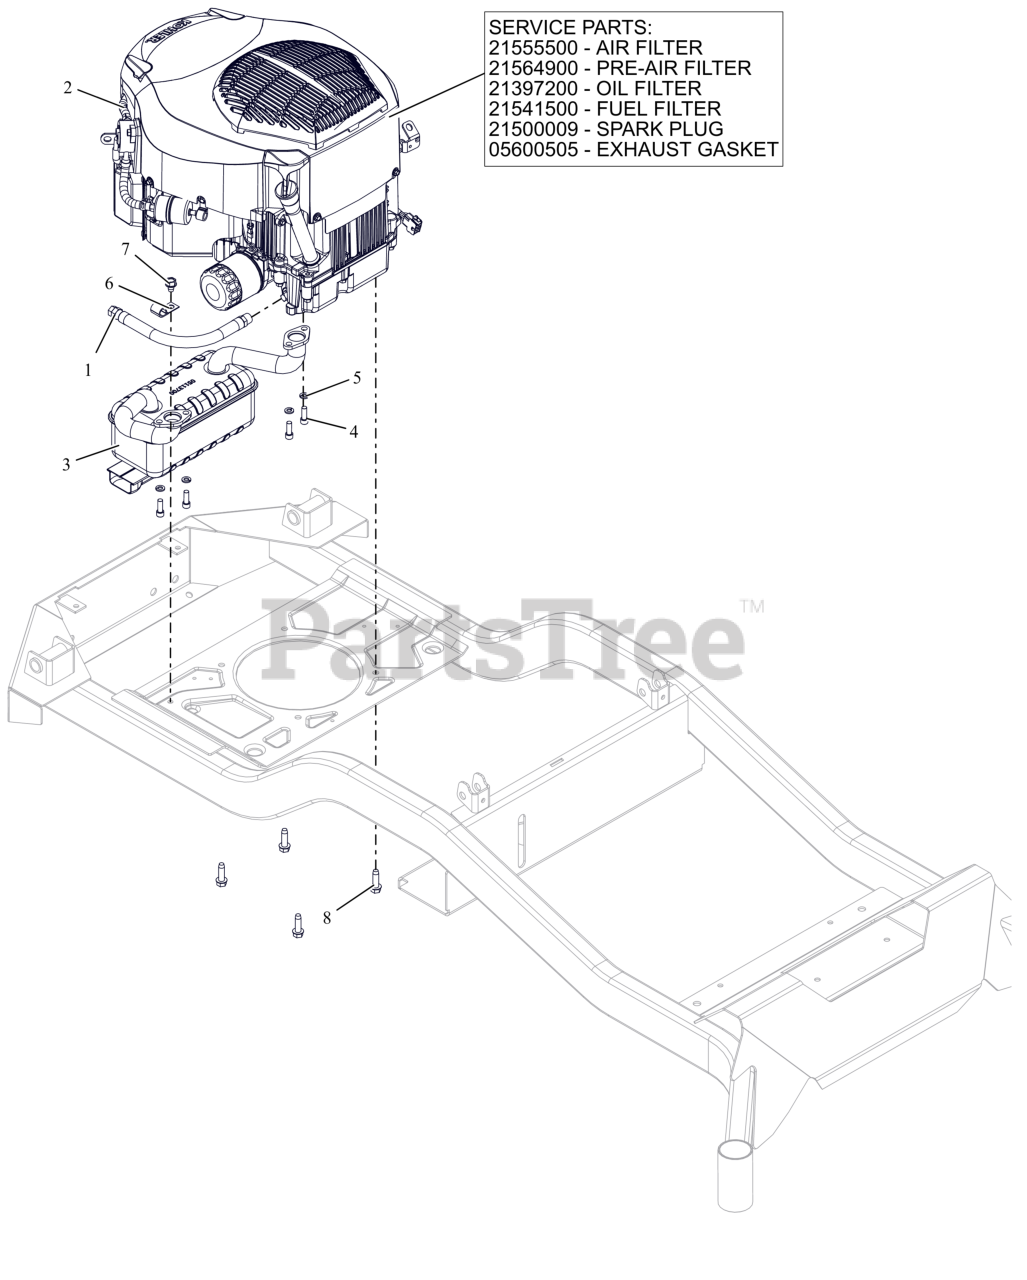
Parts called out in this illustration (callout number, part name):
1	Hose, Oil Drain
2	ENGINE, KOHLER - KT730
2	AIR CLEANER, KOHLER
2	PRE-CLEANER, KOHLER
2	FILTER, OIL - KOH CV20
2	FILTER, FUEL
2	PLUG, SPARK KOHLER
2	GASKET, MUFFLER COURAGE TWIN
3	MUFFLER, KOHLER
4	SCR-CAP .31-18X.88 S/HD G8 ZCC
5	WSHR,LK-REG .312X.078 ZCC
6	J-CLAMP
7	SCR,TAP .375-16X.50 HWH TR ZCC
8	SCR,TAP .375-16X1.25HWH TR ZCC
